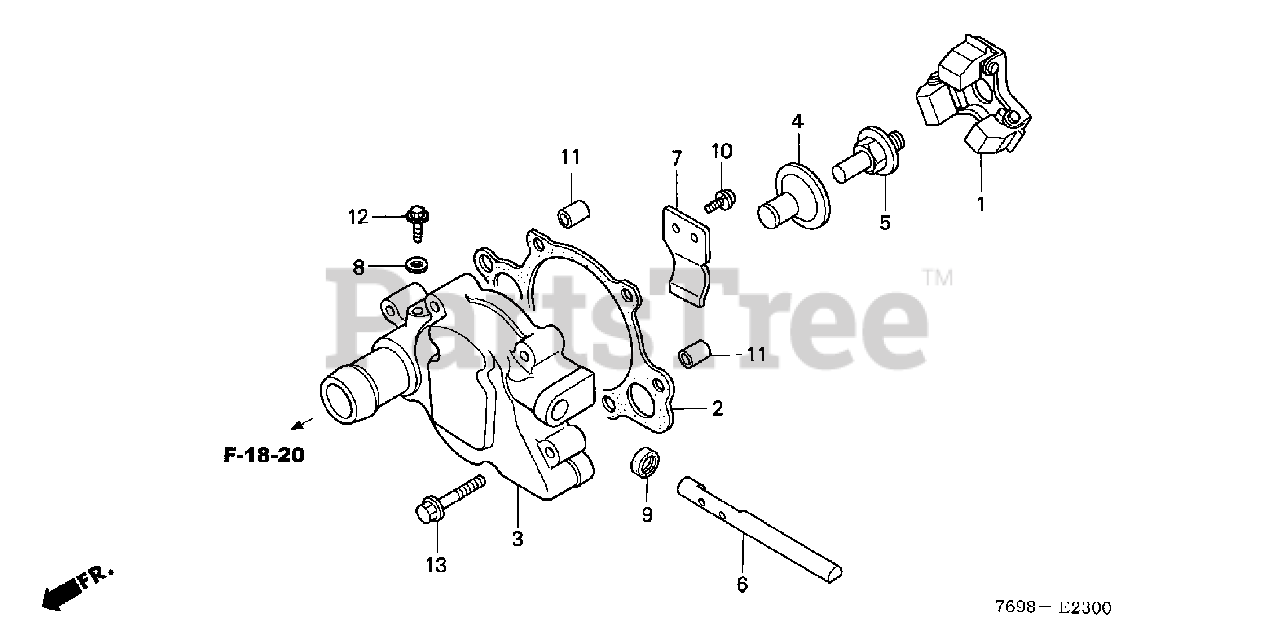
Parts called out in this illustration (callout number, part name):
1	WEIGHT, GOVERNOR
2	GASKET, GOVERNOR COVER
3	COVER, GOVERNOR
4	SLIDER, GOVERNOR
5	SHAFT, GOVERNOR
6	SHAFT, GOVERNOR
7	FORK, GOVERNOR
8	WASHER, SEALING (6MM)
9	OIL SEAL (10X16X4.5)
10	SCREW-WASHER (5X12)
11	PIN A, DOWEL (8X14)
12	BOLT, FLANGE (6X14)
13	BOLT, FLANGE (6X35)
